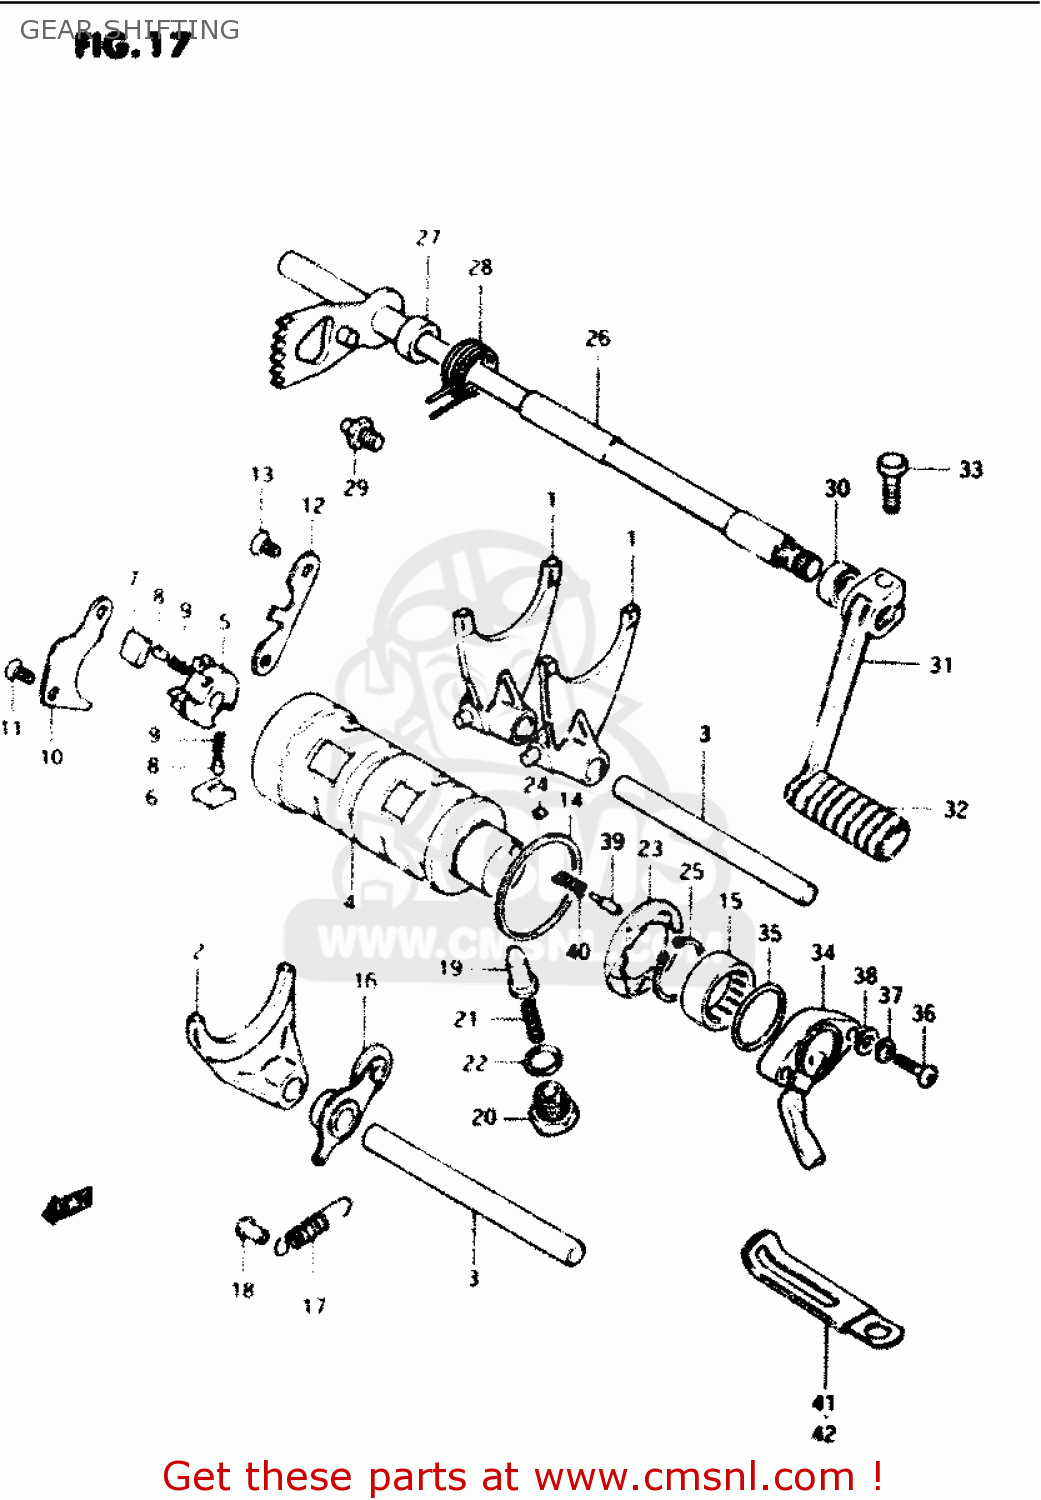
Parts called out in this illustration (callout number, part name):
1	FORK,GEAR SHIFT NO.1
2	FORK,GEAR SHIFT NO.3
3	SHAFT,GEAR SHIFT FORK
4	CAM,GEAR SHIFT
5	GEAR,GEARSHIFT CAM DRIVE
6	PAWL,GEAR SHIFT NO.1
7	PAWL,GEAR SHIFT NO.2
8	PIN(5X8)
9	SPRING
10	LIFTER,GEAR SHIFT PAWL
11	SCREW
12	GUIDE,GEAR SHIFT CAM
13	SCREW
14	WASHER(40X45X1)
15	BEARING(25X32X12)
16	STOPPER,GEAR SHIFTING
17	SPRING
18	RIVET
19	STOPPER,GEAR SHIFT CAM NO.2
20	HOLDER,GEAR SHIFT CAM STOP SPR
21	SPRING
22	GASKET(14X19.2X2) (NAS)
23	PLATE,GEAR SHIFT CAM STOPPER
24	PIN 4X6
25	CIRCLIP,25MM
26	SHAFT,GEAR SHIFT
27	SPACER (12X20X12)
28	SPRING
29	STOPPER,GEAR SHIFT CAM
30	OIL SEAL
31	LEVER ASSEMBLY,GEAR SHIFTING
32	RUBBER,PEDAL
33	BOLT
34	TERMINAL BASE ASSY,GEAR SHIFT
35	O-RING (D:2.4 ID:26.2)
36	SCREW
37	LOCK WASHER
38	WASHER
39	PIN(5X15.5)
40	SPRING
41	CLAMP
42	CLAMP
